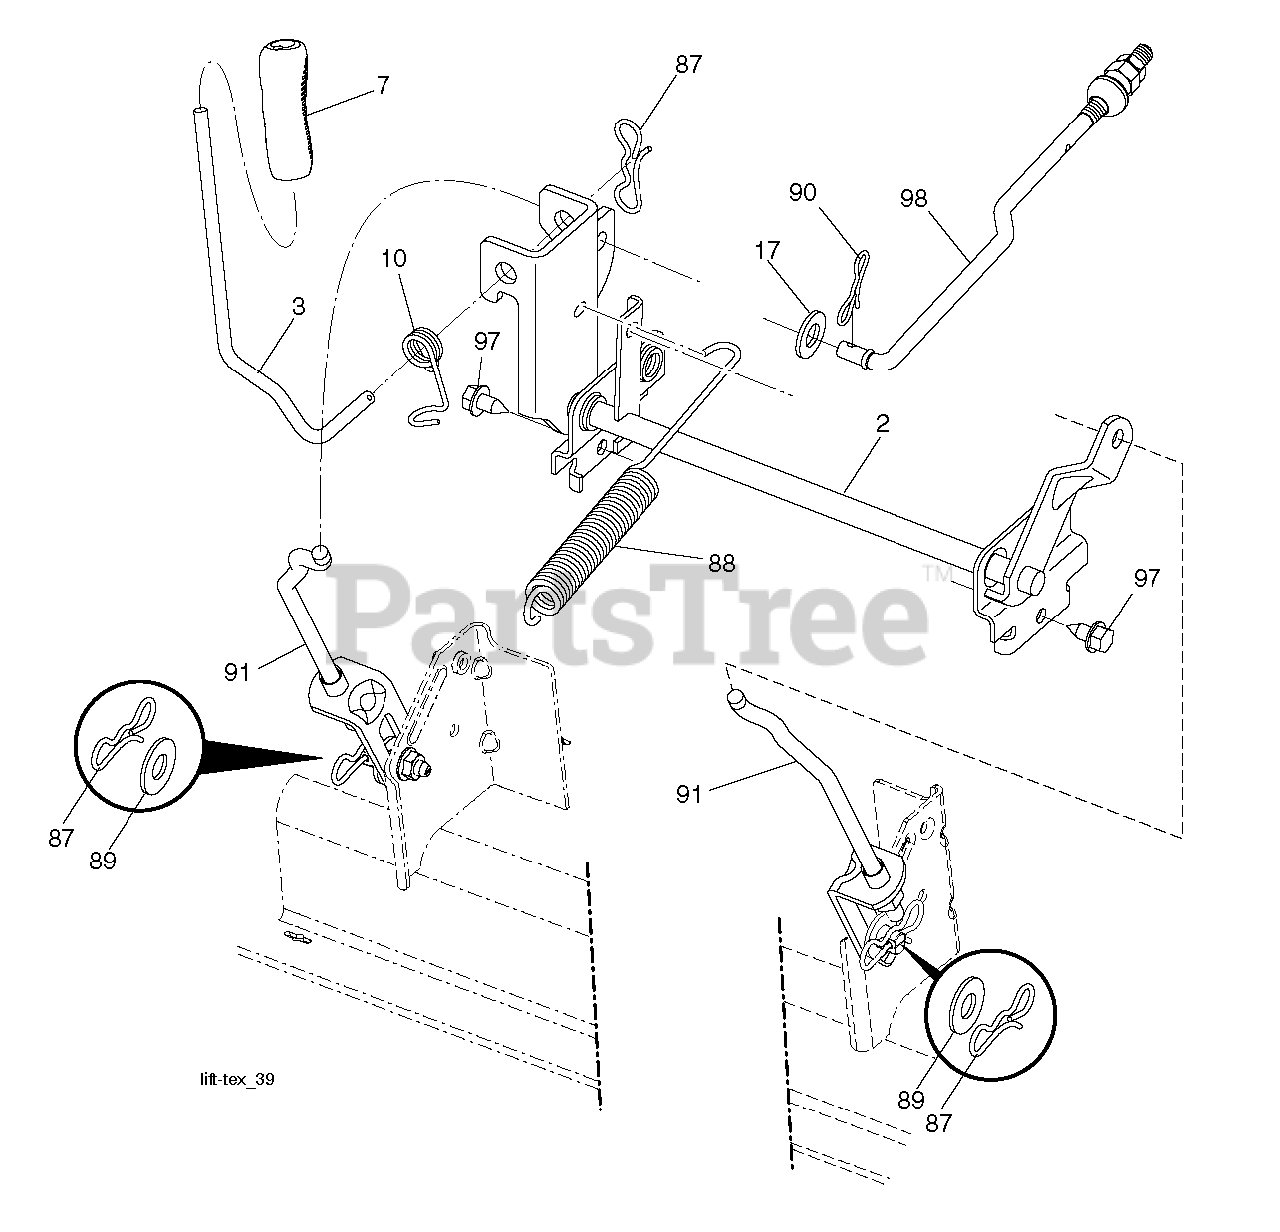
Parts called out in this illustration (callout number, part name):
2	SHAFT.ASM.CROSS.LIFT
3	LEVER.LIFT.HANDLE.LT
7	GRIP.HANDLE.LIFT.PVC.BLACK
10	SPRING.TORSION.LIFT.HANDLE
17	WASHER
87	PIN.COTTER.7/16.BOW TI.
88	SPRING.LIFT.ASSIST
89	WASHER.CLEAR.ZINC
90	PIN.COTTER.5/16.BOW TI
91	LINK.ASM.LIFT.REAR
97	SCREW, 3/8-16X3/4
98	LINK.ASM.SUSP.FRONT.MW
